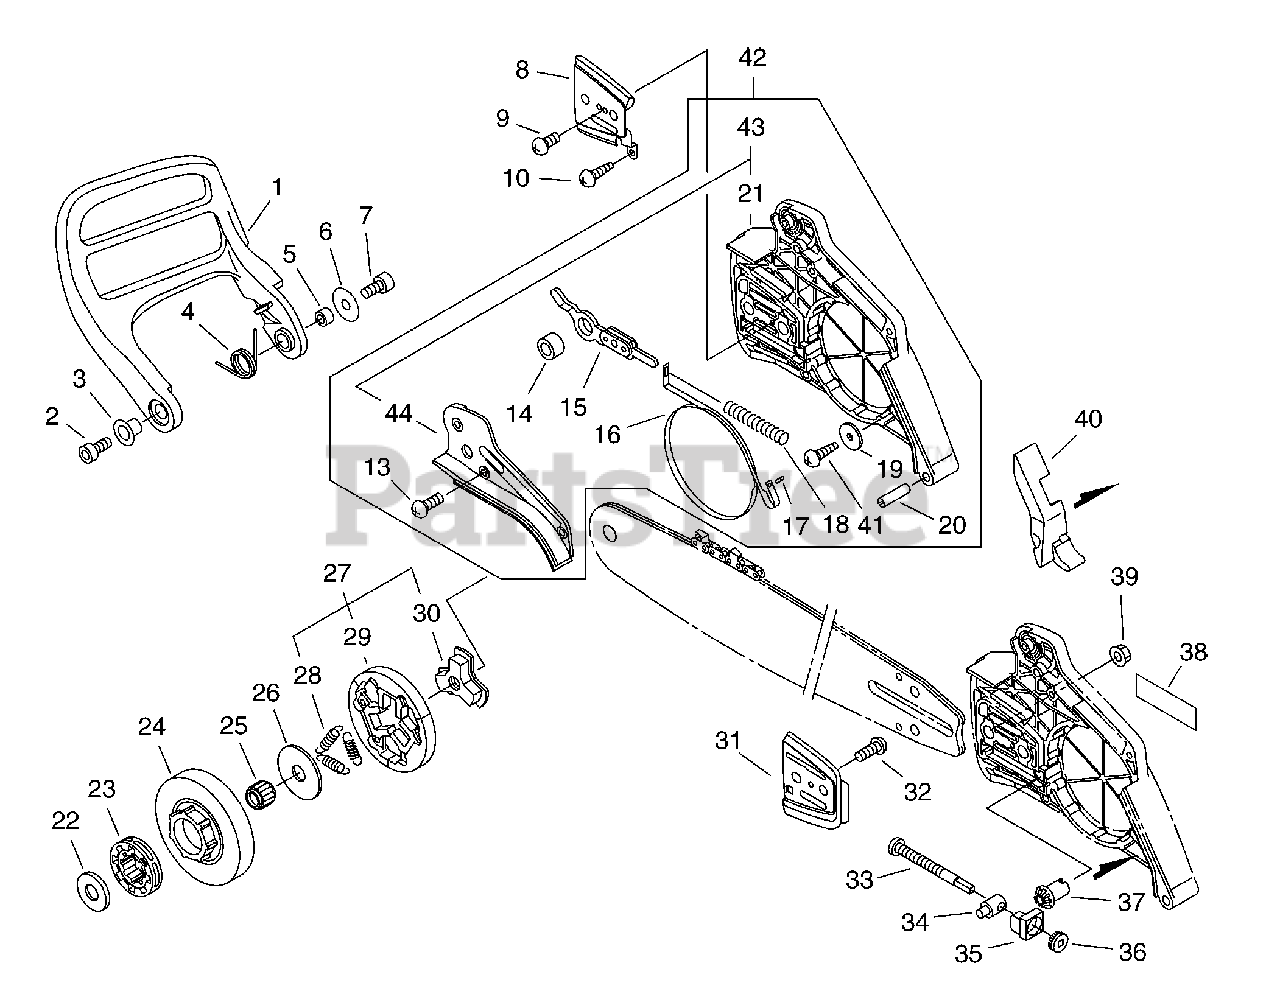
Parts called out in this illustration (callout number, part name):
1	LEVER, BRAKE
2	BOLT 5×30
3	COLLAR 10
4	SPRING, TORSION
5	SPACER 8×12×9
6	WASHER 4.2×16.5×1
7	BOLT 4×14
8	PLATE, GUIDE - OUTER
9	SCREW 3×6
10	SCREW 4×12
12	COVER, BRAKE
13	SCREW 4×12
14	SPACER 8×12×9
15	CONNECTOR, BRAKE
16	BAND, BRAKE
17	PIN 3×12
18	SPRING, COMPRESSION
20	PIN, SPRING 6×25
21	GUARD, SPROCKET
22	PLATE, CLUTCH
23	SPROCKET, 0.325 RIM
24	DRUM, CLUTCH
25	BEARING, NEEDLE
26	PLATE, CLUTCH
27	CLUTCH ASSY
28	SPRING, TENSION
29	SHOE SET, CLUTCH (3PCS)
30	HUB, CLUTCH
31	PLATE, GUIDE - INNER
32	SCREW 4×6
33	SCREW, CHAIN TENSION
34	TENSIONER, CHAIN
35	COLLAR 8
36	GEAR, BEVEL
37	GEAR, BEVEL
38	LABEL, ECHO
39	NUT, FLANGE M8×1.25
40	CUSHION
41	SCREW 4×16
42	BRAKE ASSY, CHAIN
43	SPROCKET GUARD KIT
44	COVER, BRAKE
